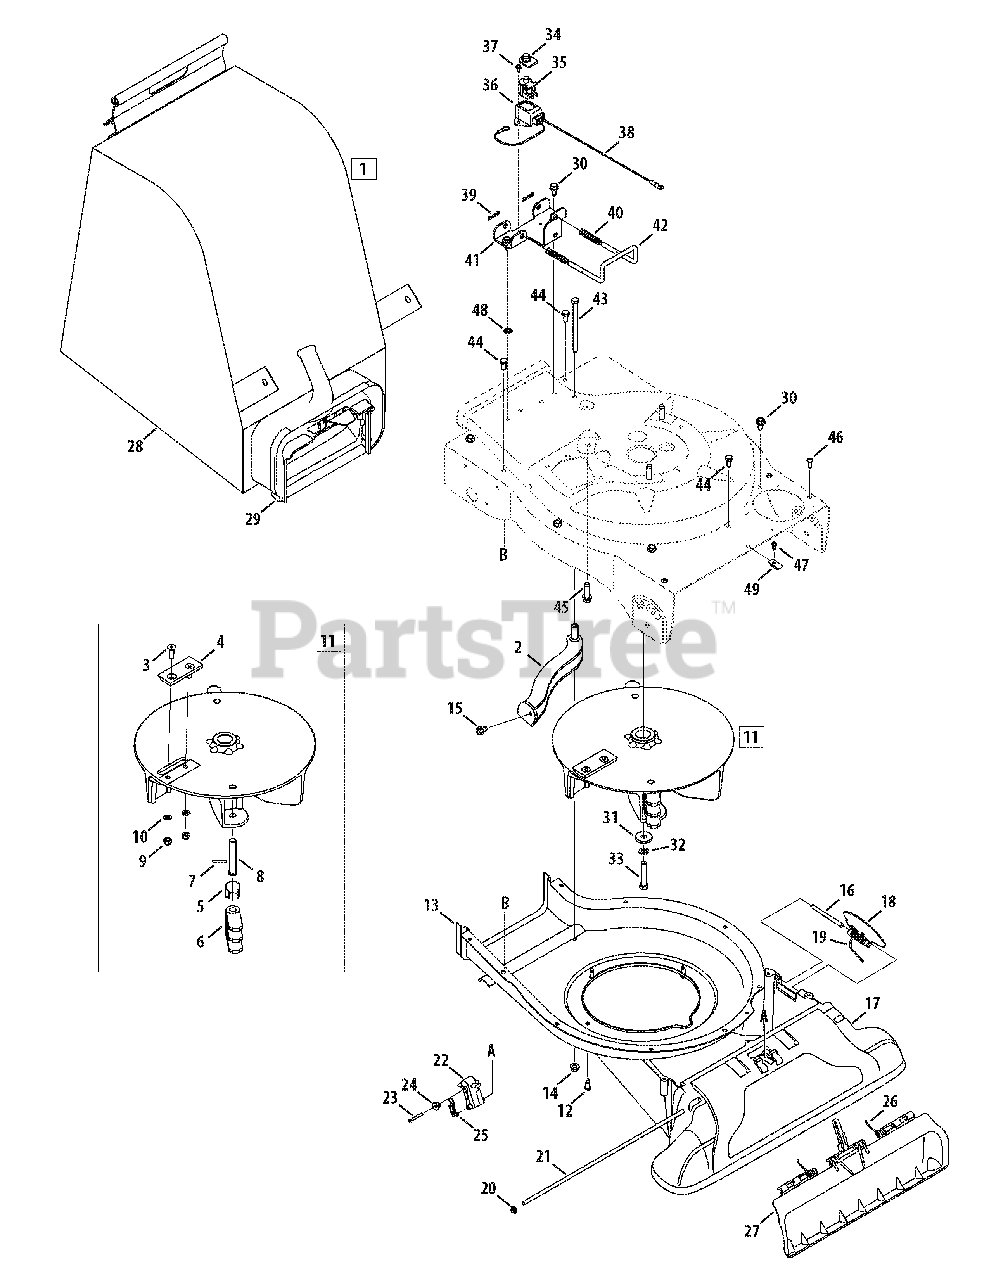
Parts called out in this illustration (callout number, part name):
1	Bag Assembly
3	Hex Screw 5/16-24 x 1.0
4	Chipper Blade
7	Spiral Pin
8	Clevis Pin
9	Lock Nut, 5/16-24
10	Lock Washer, 5/16
11	Impeller Assembly
12	Shoulder Screw, #12-24 x.30 x.46
14	Flange Lock Nut 5/16-18
15	Screw, 5/16-18 x.500
17	Nozzle
18	Base Adapter Door
19	Torsion Spring
20	Cap Speed Nut 1/4
21	Pivot Rod
22	Nozzle Door Lever
23	Hex Screw, #8-18 x 1.25
24	Shoulder Spacer
25	Extension Spring
26	Nozzle Door Torsion Spring
27	Nozzle Door
29	Chute Assembly
30	Hex Index Screw, 5/16-12 x.750
31	Flat Washer.375 ID x 1.25 OD
32	Lock Washer 3/8
33	Hex Cap Screw 3/8-24 x 2.0
34	Switch Cover
35	Safety Switch
36	Safety Switch Cover
37	Hex Washer Screw #10-16 x.50
38	Wire Harness
39	Cotter Pin
40	Compression Spring
43	Hex Cap Screw 5/16-18 x 4.5
44	Hex Cap Screw 5/16-18 x.625
45	Hex Washer Screw 3/8-16 x 1.00
46	Screw, #12-16 x.750
47	Screw #10 - 16 x.500
48	External L-Washer 5/16
49	Speed Nut
